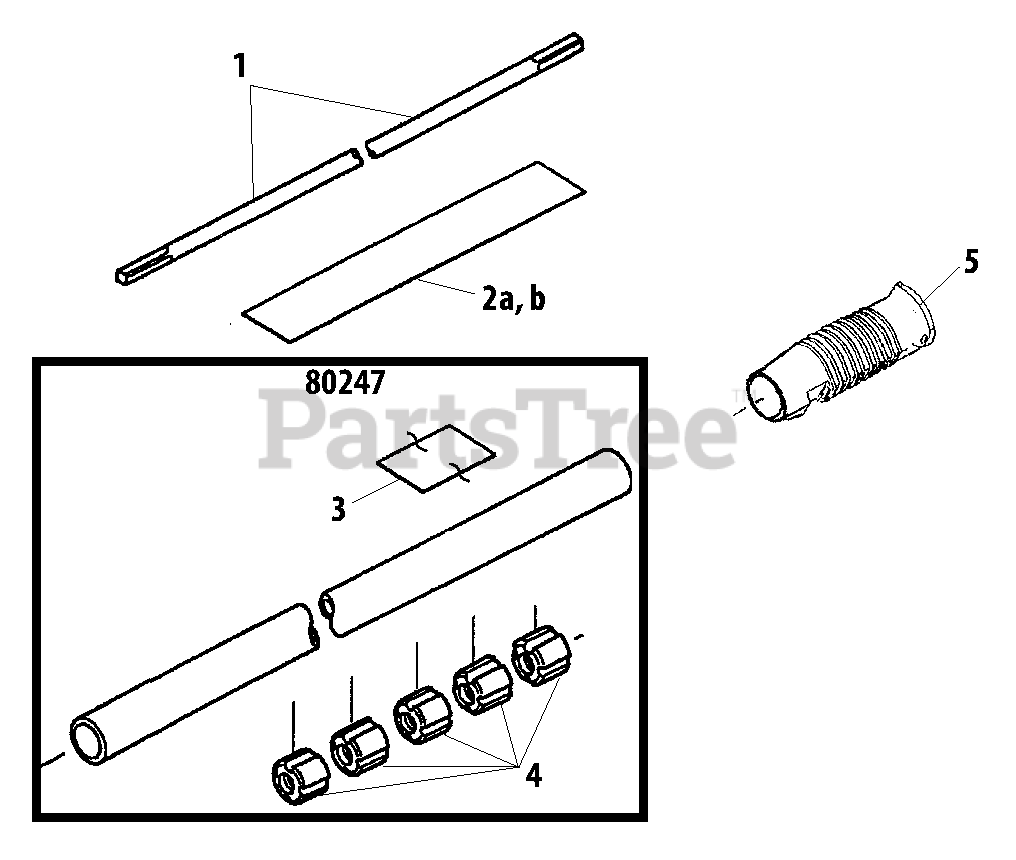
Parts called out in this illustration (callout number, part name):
1	PIPE, MAIN
2A	LABEL - MODEL
2B	LABEL - MODEL
3	LABEL - CAUTION
4	BUSHING
5	GRIP - REAR
80247	MAIN PIPE ASSY
